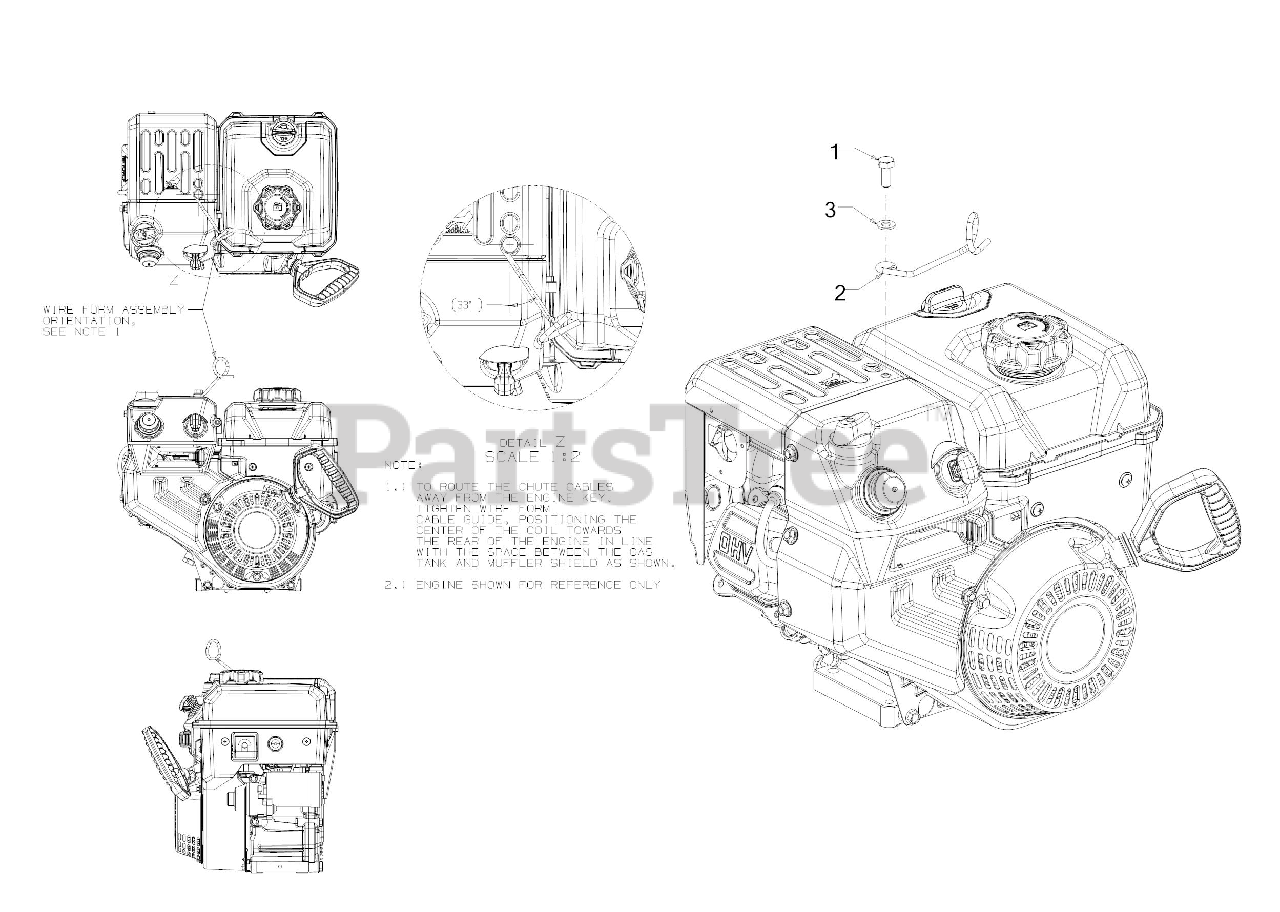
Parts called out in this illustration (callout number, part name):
1	HEX SCREW M8-1.25 x 20 GR8
2	CHUTE CABLE GUIDE
3	FLAT WASHER
